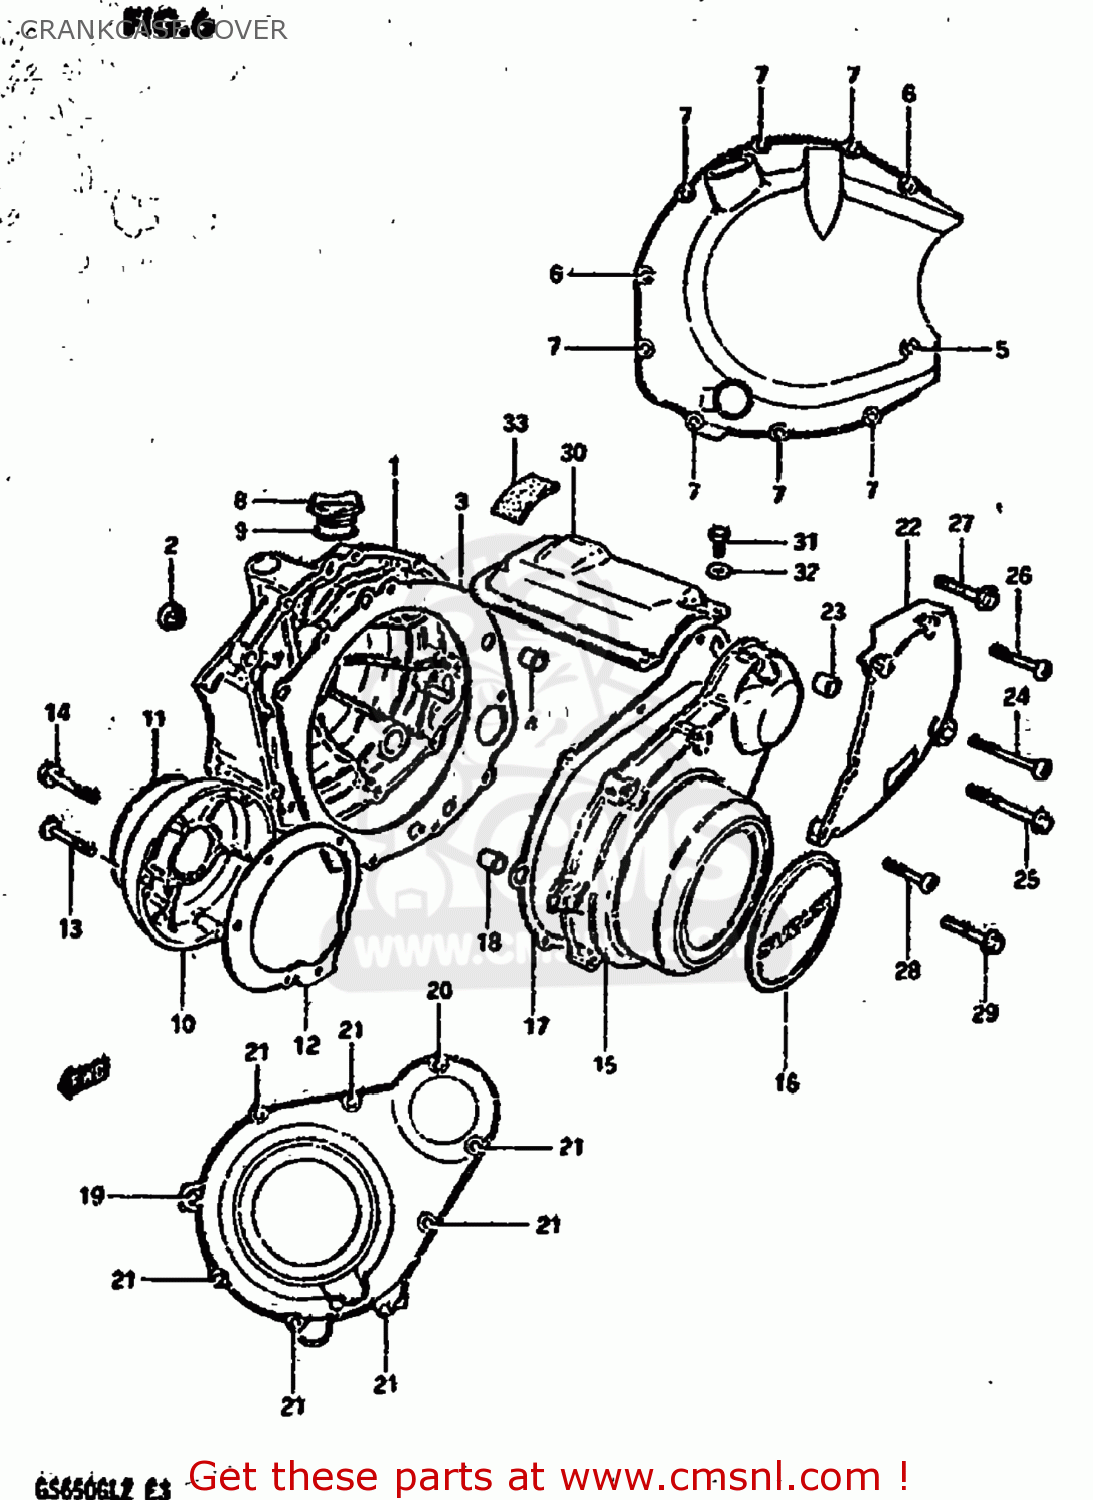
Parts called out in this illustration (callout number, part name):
1	COVER,CLUTCH
2	LENS,OIL LEVEL CHECK
3	GASKET,CLUTCH COVER (MCA)
4	PIN
5	SCREW 6X65
6	SCREW
7	SCREW 6X30
8	PLUG
9	O-RING
10	COVER,CONTACT BREAKER
11	EMBLEM,CONTACT BREAKER COVER
12	GASKET,CONTACT BREAKER COVER (NAS)
13	SCREW
14	BOLT (5*30)
15	COVER
16	EMBLEM,MAGNETO COVER
17	GASKET,MAGNETO COVER (MCA)
18	PIN
19	BOLT
20	SCREW
21	SCREW
22	COVER,SPROCKET
23	PIN
24	SCREW
25	BOLT (6X40)
26	SCREW 6X30
27	BOLT (6X30)
28	SCREW
29	BOLT
30	COVER
31	BOLT 5X16
32	WASHER
33	DAMPER,STARTER MOTOR CLUTCH
